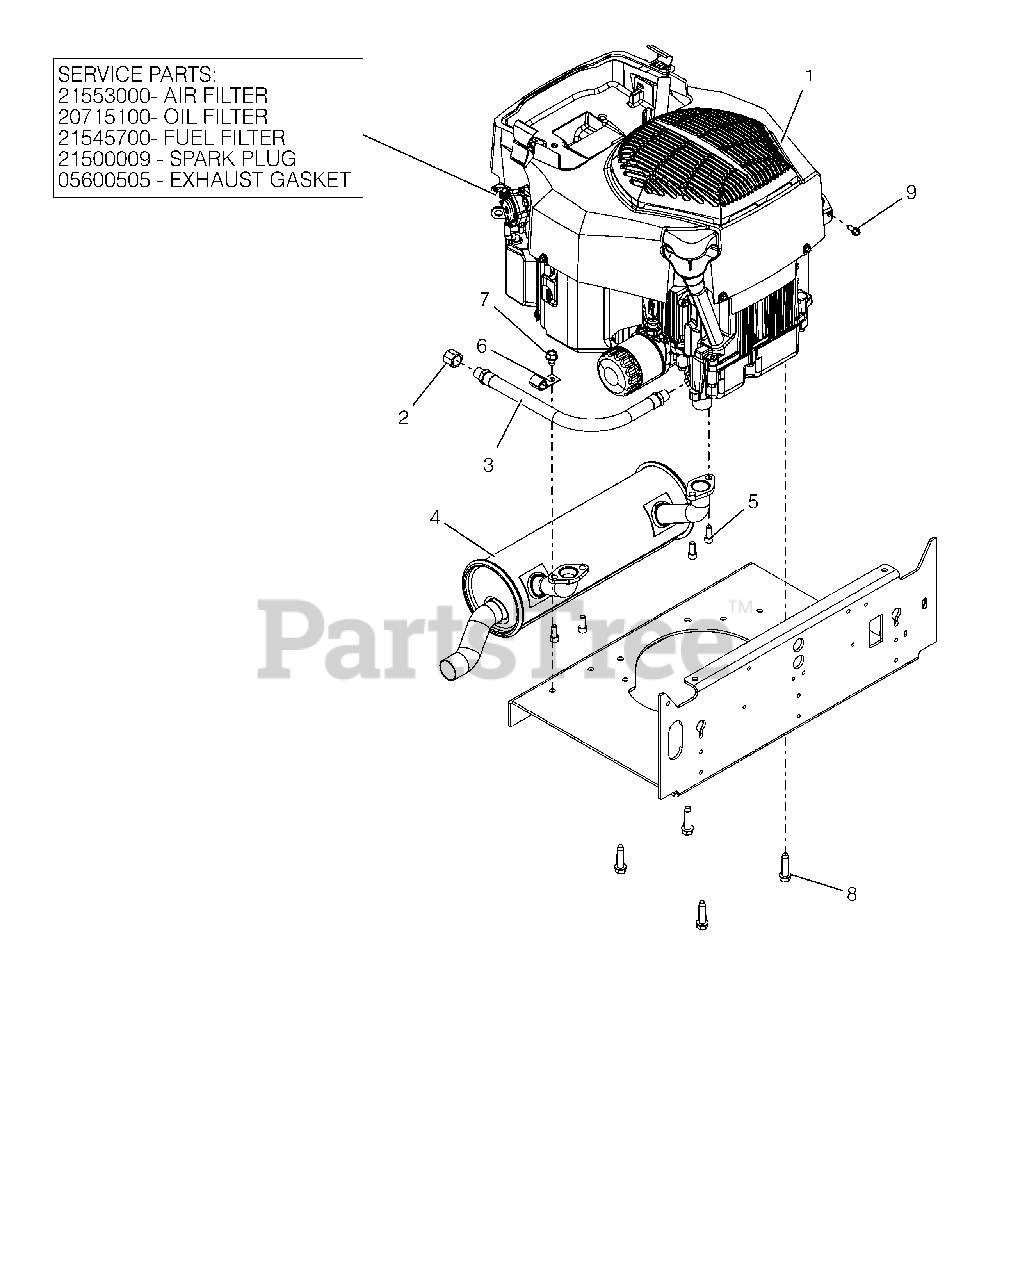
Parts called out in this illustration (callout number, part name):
1	ENGINE, KOHLER ZT740
1	AIR FILTER, KOHLER
1	OIL FILTER KOHLER
1	FILTER-FUEL KOHLER COURAGE PRO
1	PLUG, SPARK KOHLER
1	GASKET, MUFFLER KOHLER TWIN
2	PIPE CAP 3/8 NPT FEMALE
3	HOSE,HYD .38-14-0K M6N0-M6N0
4	MUFFLER, ZT730/ZT740
5	SCR-CAP .31-18X.75 S/HD
7	@SCR-TAP .38-16X.50 HWH TR YWZ
8	@SCR-TAP .38-16X1.50 HWH TR YZ
9	@SCR-TAP .25-20X.62 HWH TR YWZ
